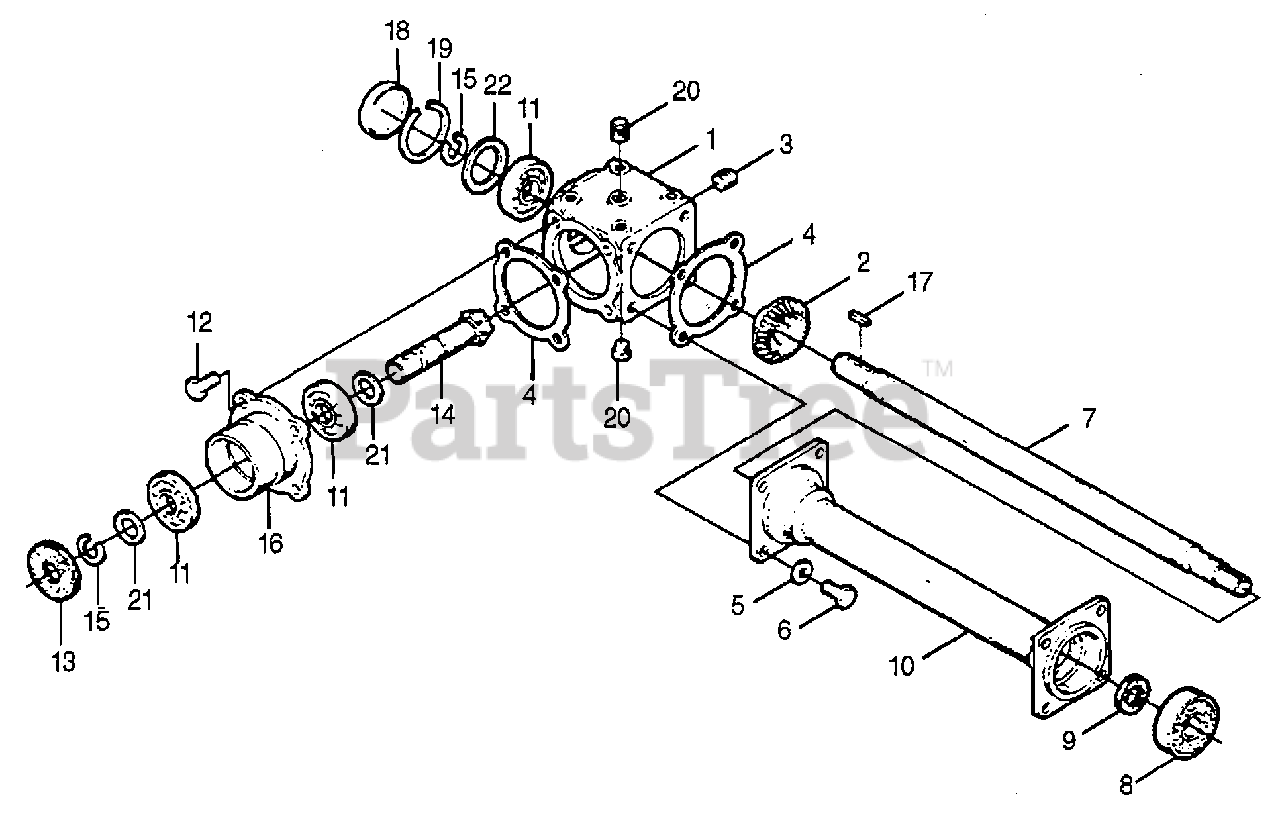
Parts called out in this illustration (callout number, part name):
2	CROWN WHEEL (25-TOOTH) (NOT AVAILABLE)
5	WASHER (10MM)
6	SCREW, CAP (10X20) (GR 8.8) (NOT AVAILABLE)
8	BEARING (NOT AVAILABLE)
9	OIL SEAL (30X47X7)
10	EXTENSION (NOT AVAILABLE)
11	BEARING (NOT AVAILABLE)
12	SCREW, CAP (10X22) (GR 8.8)
13	OIL SEAL (25X62X7)
14	PINION, BEVEL (9-TOOTH) (NOT AVAILABLE)
15	CIRCLIP (OUTER)
16	EXTENSION
17	KEY, PARALLEL (8X7X25)
19	CIRCLIP (INNER)
21	SHIM (.3MM) (NOT AVAILABLE)
21	SHIM (.4MM) (NOT AVAILABLE)
21	SHIM (.5MM) (NOT AVAILABLE)
21	SHIM (1.0MM) (NOT AVAILABLE)
22	SHIM (.3MM)
22	SHIM (.4MM)
22	SHIM (.5MM) (NOT AVAILABLE)
22	SHIM (1.0MM) (NOT AVAILABLE)
